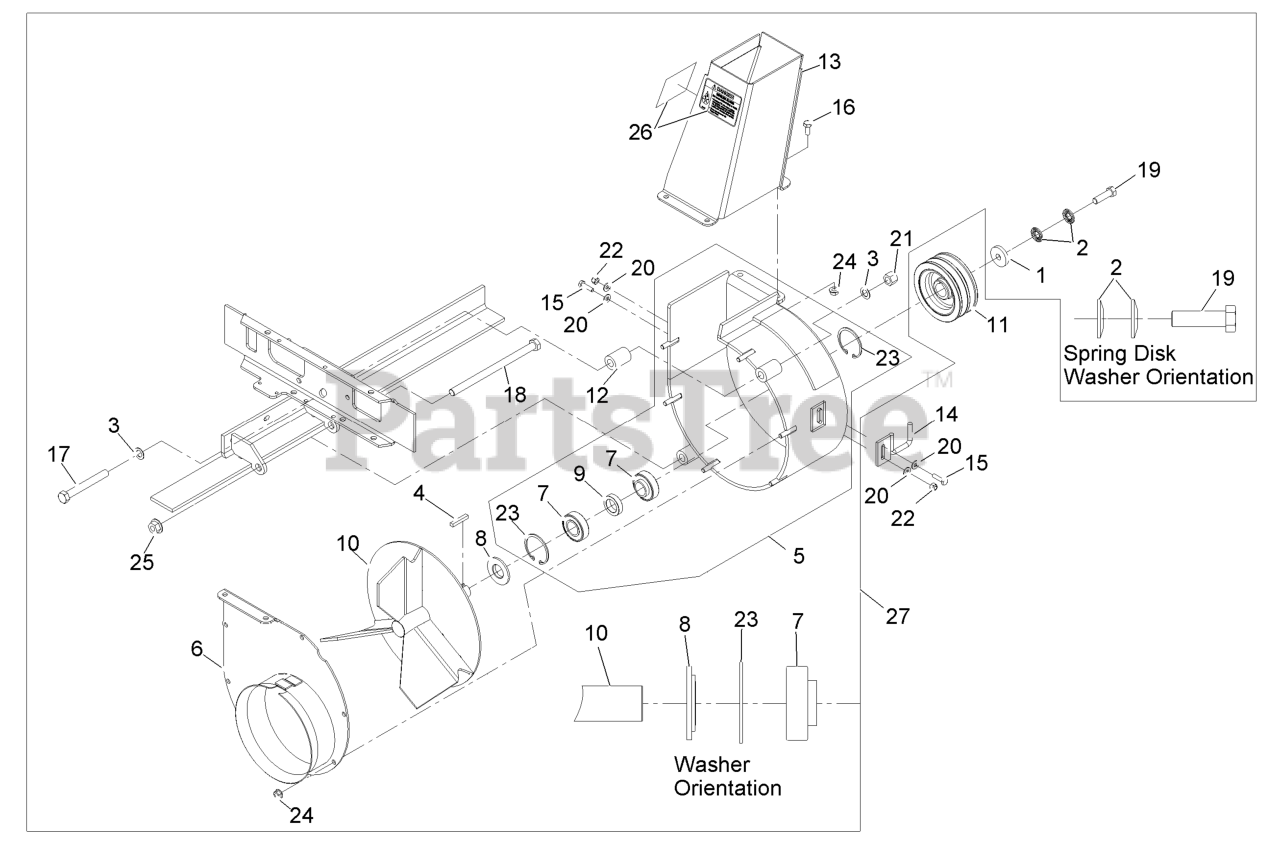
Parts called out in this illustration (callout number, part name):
1	WASHER-CLUTCH
2	WASHER-SPRING
3	WASHER-THRUST
4	KEY-SQUARE
5	ASM,HOUSING W/BEARINGS
6	COVER-BLOWER
7	BEARING-BALL
8	SPACER-BLOWER
9	SPACER-BEARING
10	IMPELLER-3 BLADE
12	SPACER-MOUNT
13	DISCHARGE CHUTE ASM
15	SCREW-HH
16	SCREW-HH
17	SCREW-HH
18	SCREW-HH
19	SCREW-HH
20	WASHER-FLAT
21	NUT-LOCK, NI
22	NUT-LOCK, NI
23	RING-SNAP
25	NUT-HHF
26	DECAL-DANGER IMPELLER
27	ASM,BLOWER COMPLETE
